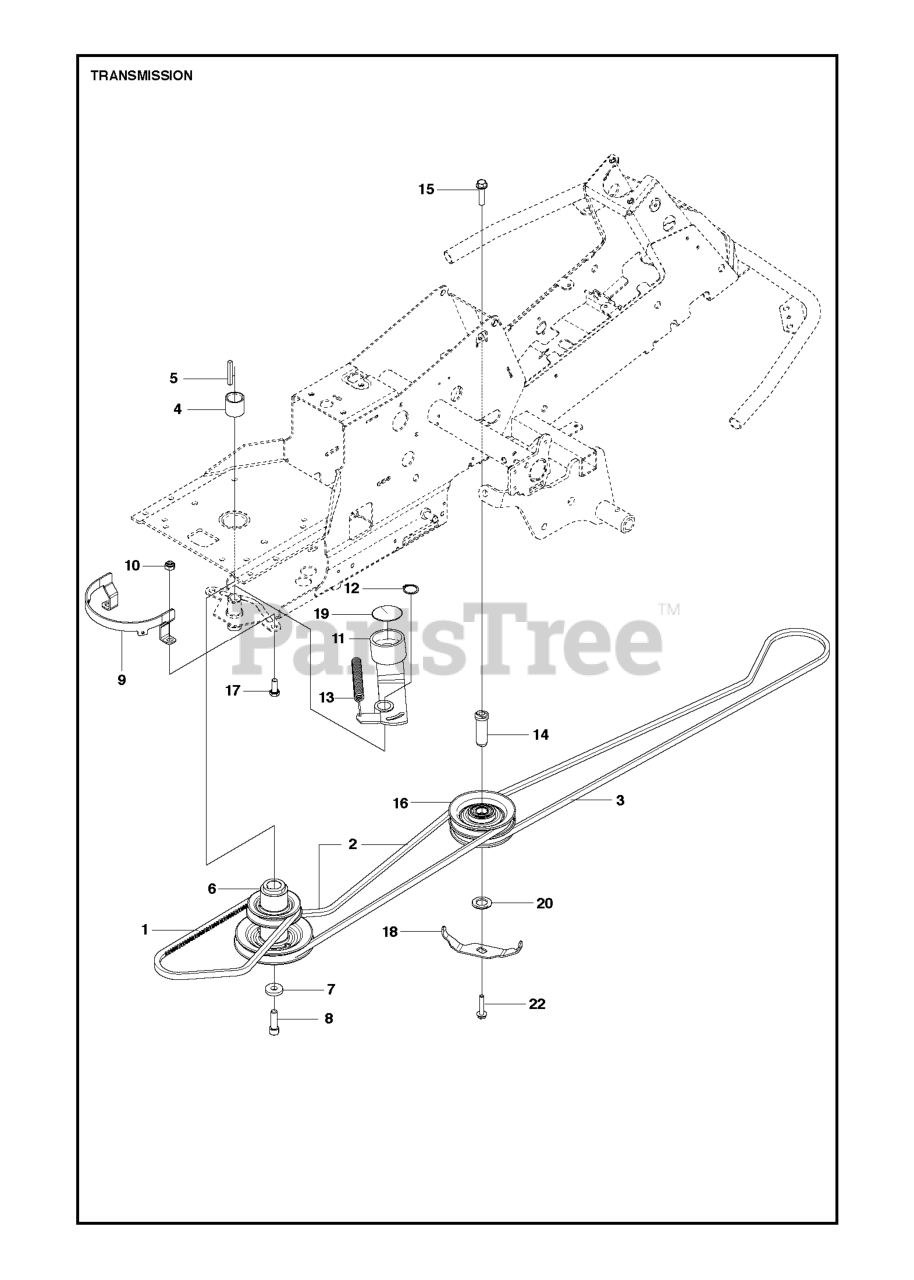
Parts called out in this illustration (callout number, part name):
3	BELT
10	NUT
12	RETAINING RING SGA 25
17	Screw M10x25
18	BELT GUIDE
